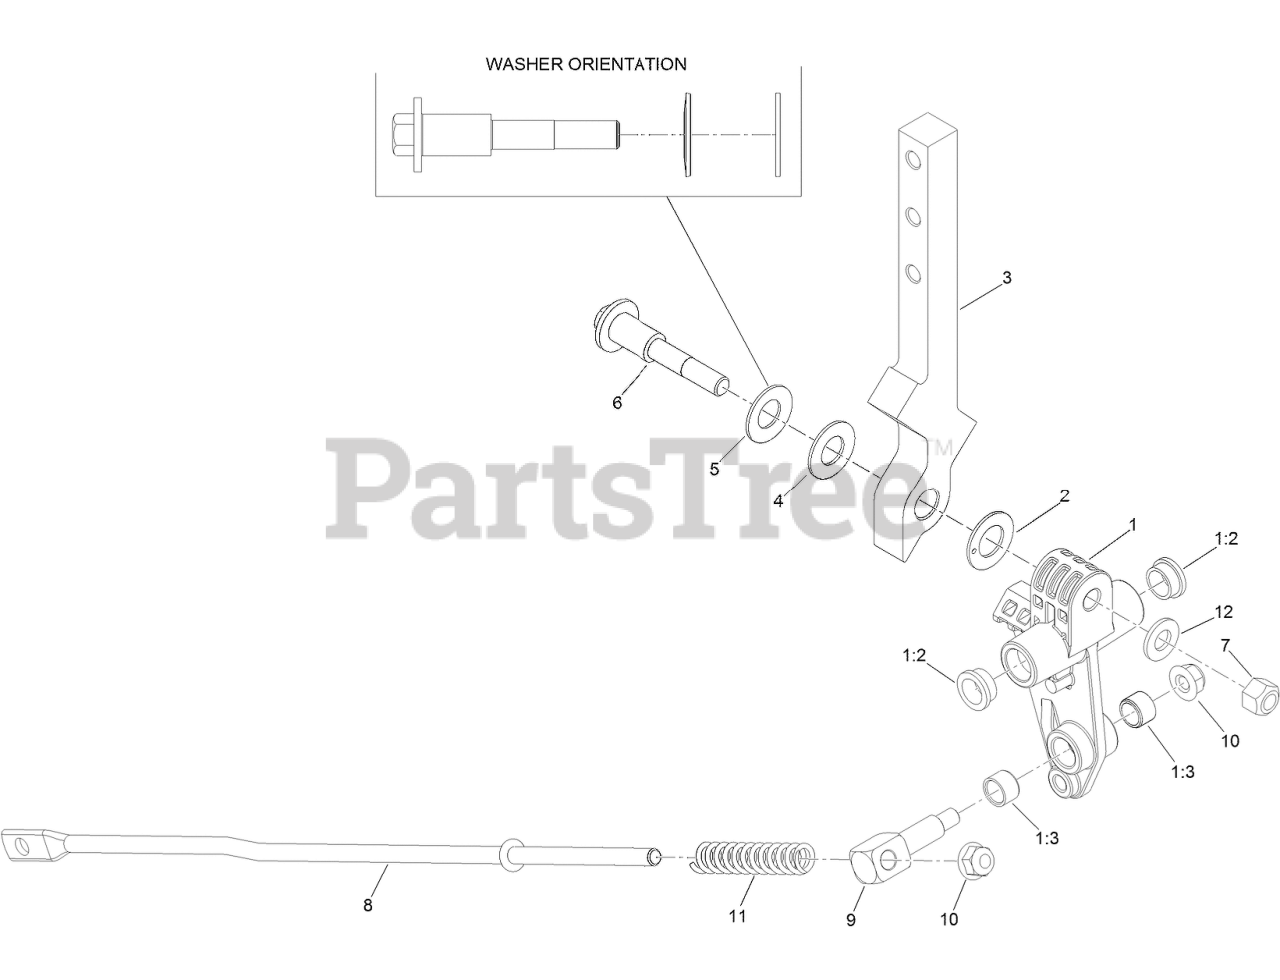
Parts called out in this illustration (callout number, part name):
1	CONTROL ARM ASM
1:2	BUSHING
1:3	BUSHING-SLEEVE
2	WASHER-FRICTION
3	ARM-CONTROL
4	WASHER
5	WASHER-BELLEVILLE
6	BOLT-PIVOT
7	NUT-LOCK, CONE
8	LINK-CONTROL
9	SWIVEL
10	NUT-HF, NI
11	SPRING-RETURN, NEUTRAL
12	WASHER-FLAT
